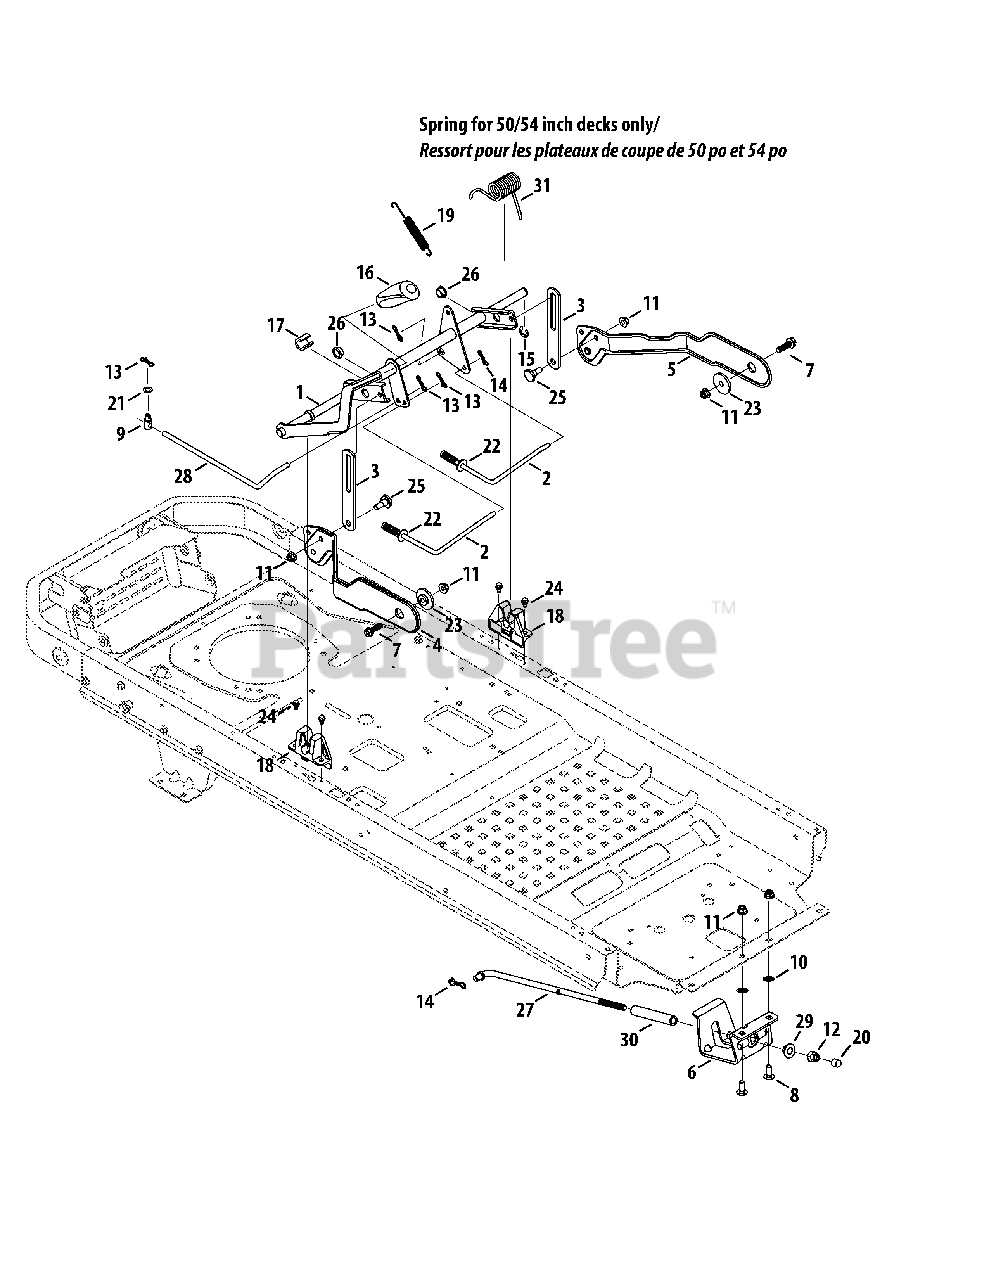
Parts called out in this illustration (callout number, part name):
1	Deck Lift Shift Assembly
2	Brake Rod Assembly
3	Lift Link Plate
4	Deck Lift Plate, RH
5	Deck Lift Plate, LH
6	Rod Support Mounting Bracket
7	Hex Washer Screw 3/8-16 x 1.250
8	Carriage Bolt 3/8-16 x 1.00
9	Ferrule 3/8-24 x .375
10	Push Nut 3/8
11	Flange Lock Nut 3/8-16
12	Flange Lock Nut 1/2-13
13	Bow-Tie Cotter Pin
14	Bow-Tie Cotter Pin
15	E-Type Ring .750
16	Grip .50 ID
17	Spacer .76 ID x .750 LG
18	Deck Lift Bracket
19	Extension Spring .63 Dia. x 4.95 LG
20	End Cap
21	Washer .375 x .700 x .030
22	Flat Washer .344 x 1.00 x .063
23	Shoulder Spacer .854 x .232
24	Shoulder Screw .500 x 1/4-20
25	Shoulder Screw .500 Dia. x .434
26	Flange Bearing .751 x 1.125 x .375
27	Deck Lift Rod
28	Brake Rod
29	Deck Lift pivot Cup
30	Nylon Sleeve .55 ID x 4.50 LG
31	Torsion Spring 1.323 x 2.83
